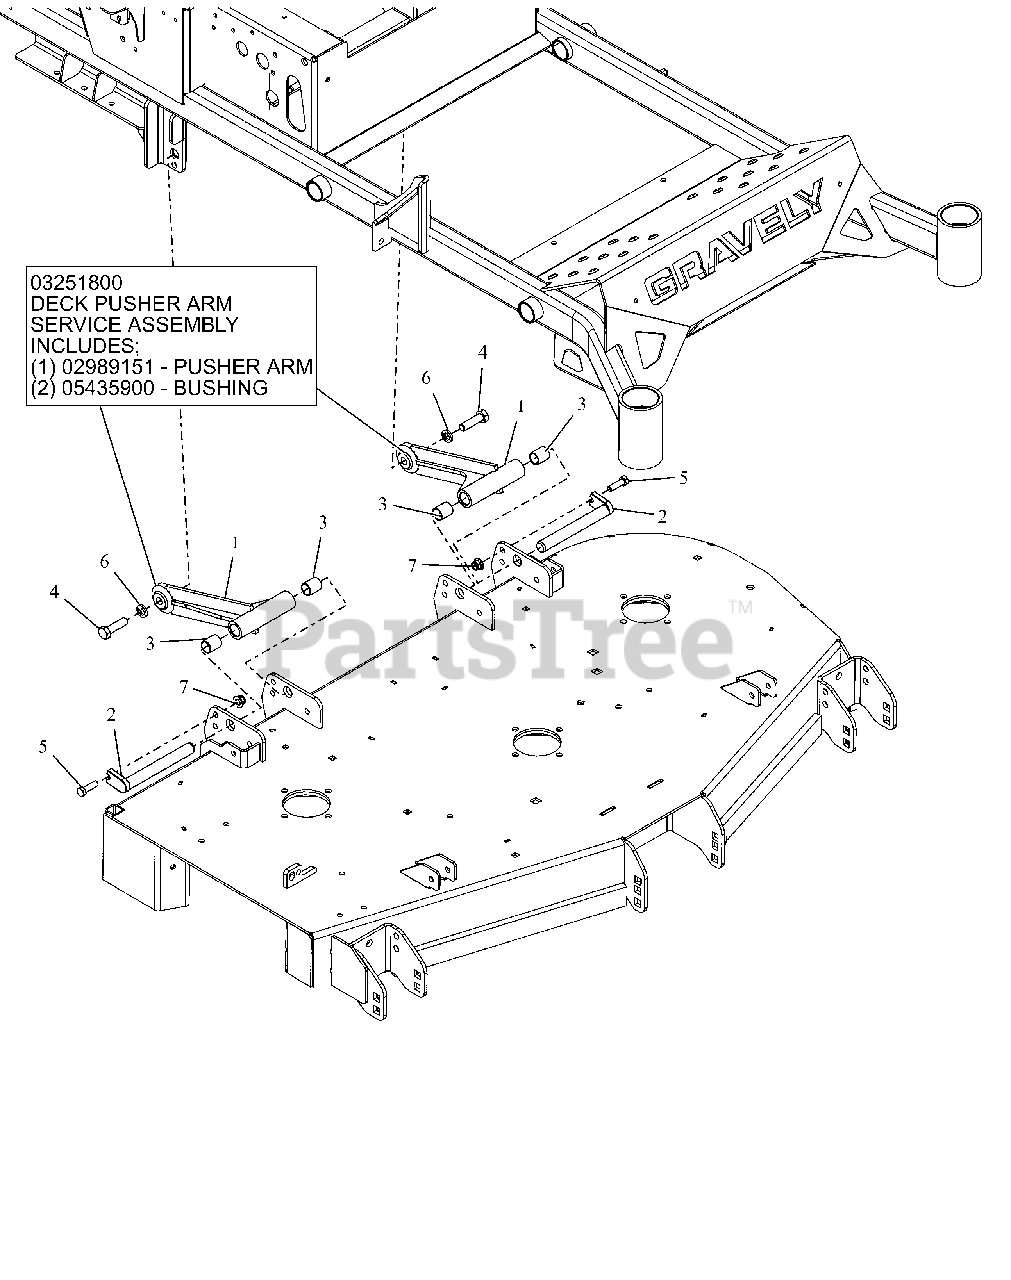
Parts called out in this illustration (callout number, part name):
1	DECK PUSHER ARM WMT - BLACK
1	DECK PUSHER ARM ASSEMBLY
2	PIN, MOWER MTG
3	BRG, .750 X .875 X 1.000
4	BLT-HEX .50-13X1.75 GR5EP80 YZ
5	@BLT-HEX .38-16X1.25 GR5 YWZC
6	@WSHR-LK .50X.125 REG YWZC
7	@NUT-LK-NYL-FLG .38-16 YWZC
